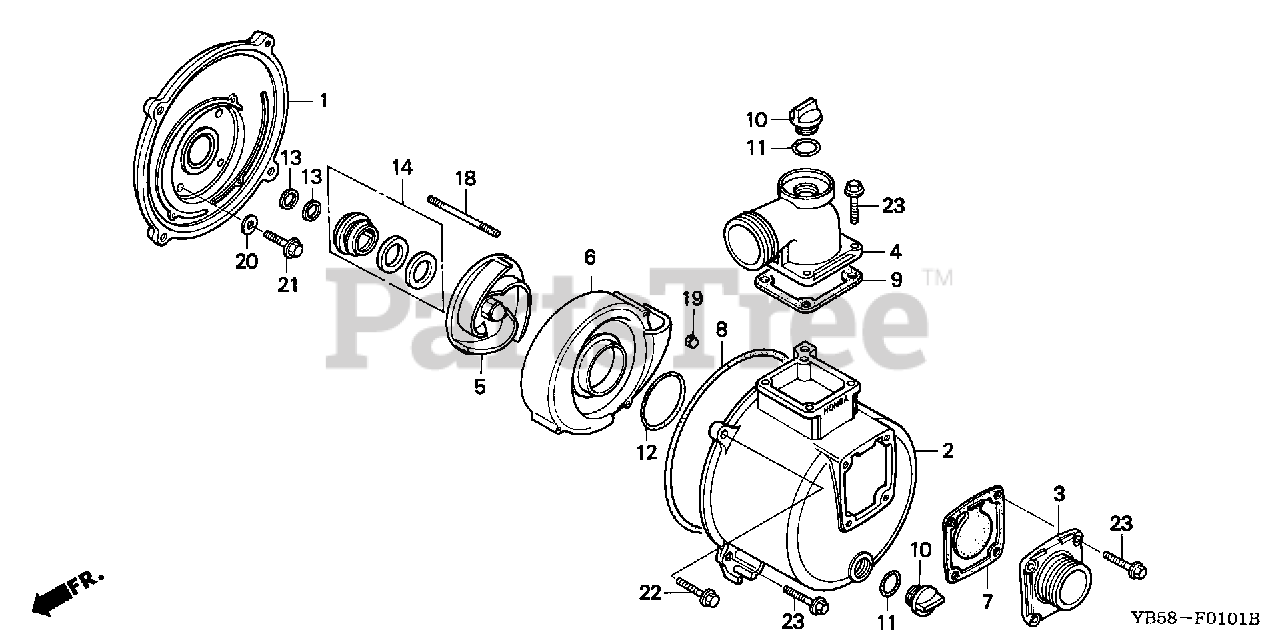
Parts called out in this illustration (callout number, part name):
1	COVER, CASING
2	CASING
3	PIPE, INLET (NPTF)
4	PIPE, OUTLET (NPTF)
6	CASE, VOLUTE
7	VALVE, IN.
8	RING, CASING SEAL
9	GASKET, OUTLET
10	CAP, FILLER
11	RING, SEAL (B)
12	O-RING (71X5.7)
13	SHIM, ADJUSTER
14	SEAL, MECHANICAL
18	BOLT, STUD (6X50)
19	NUT, CAP (6MM)
20	WASHER, SEALING (8MM)
21	BOLT, FLANGE (8X28)
22	BOLT, FLANGE (10X32)
23	BOLT, FLANGE (10X32)
